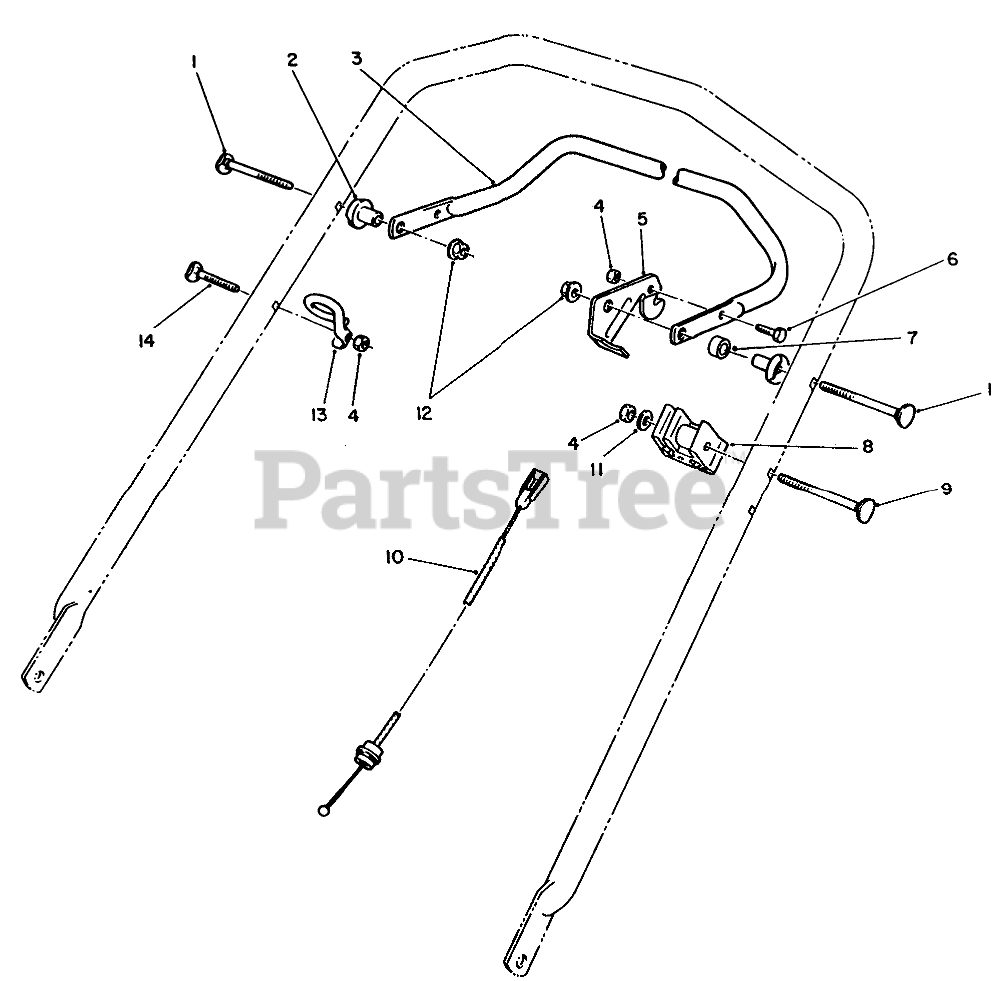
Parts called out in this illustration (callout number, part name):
1	SCREW-HANDLE
2	SPACER-SUPPORT
3	Bar-Control
4	NUT-LOCK, NI
5	LEVER-CONTROL
6	SCREW-HH
7	SPACER-NYLON
8	SUPPORT-CABLE
9	SCREW-HANDLE
10	BRAKE CABLE
11	WASHER-FLAT
12	NUT-LOCK, NI
13	GUIDE-ROPE
14	Screw-Handle
